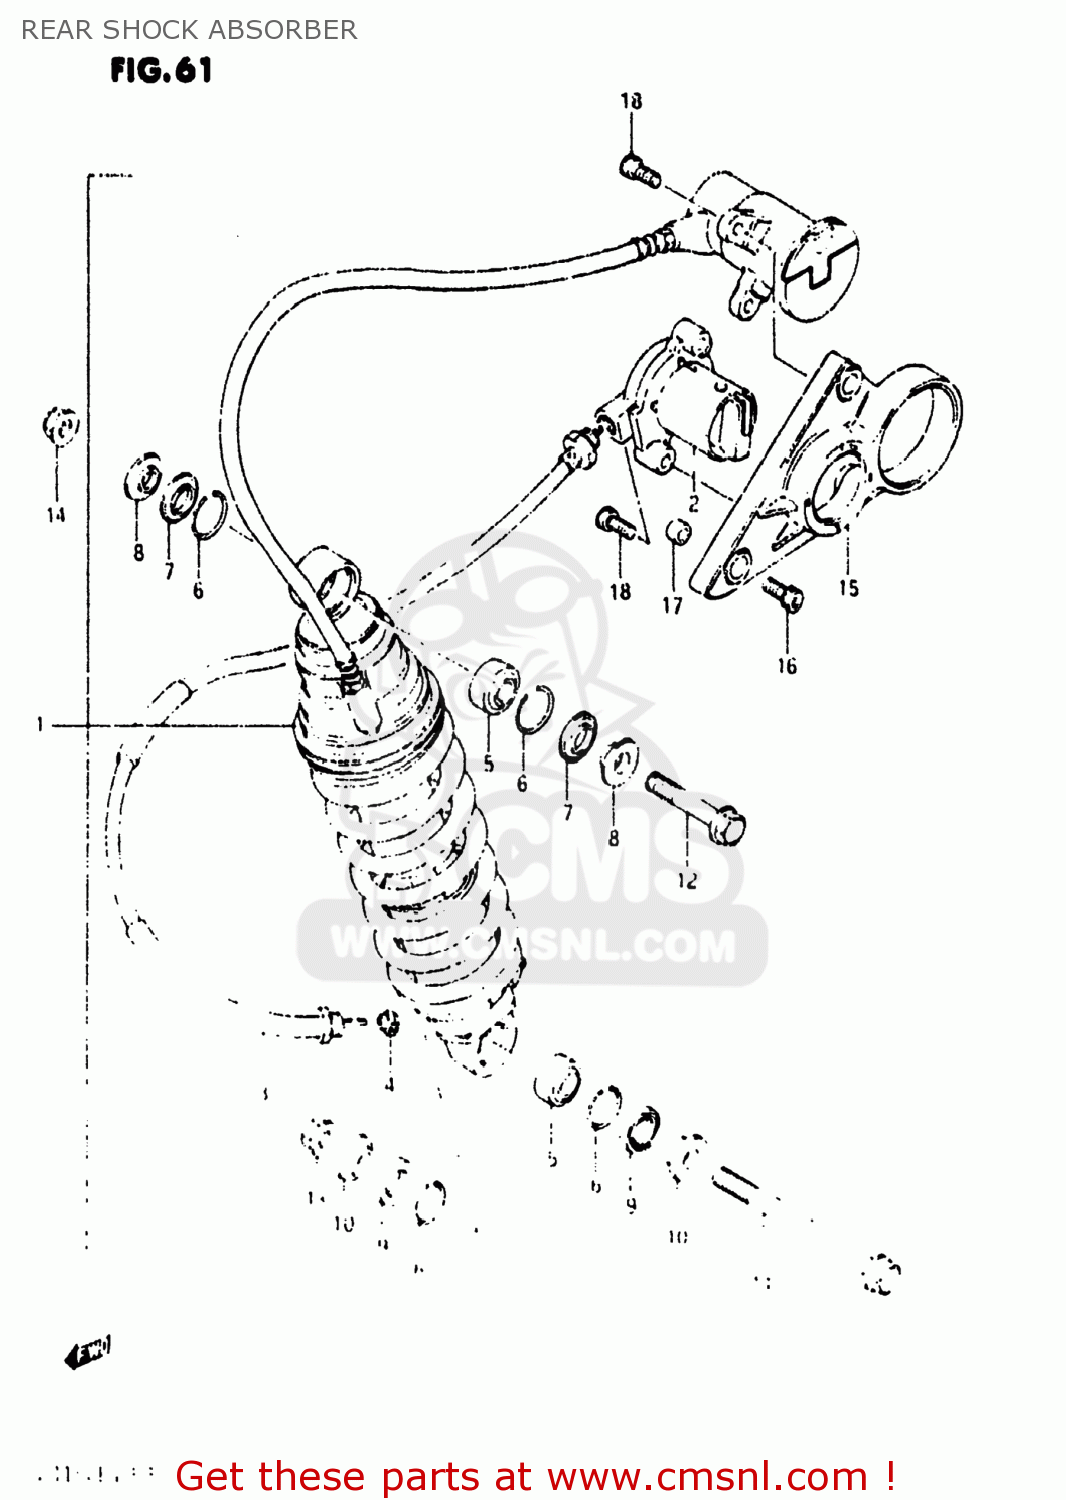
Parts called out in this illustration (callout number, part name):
1	ABSORBER ASSEMBLY,REAR SHOCK
2	ADJUSTER
3	CABLE,CONTROL
4	GEAR,DAMPER ADJUSTER
5	BEARING,REAR SHOCK ABSORBER
6	RING
7	SEAL,DUST UPR
8	COLLAR,UPR
9	SEAL,DUST
10	SPACER
11	BOLT(10X115)
12	BOLT(10X50)
13	NUT 10MM
14	NUT
15	BRACKET
16	BOLT
17	SPACER(6.5X12X6.9)
18	BOLT
